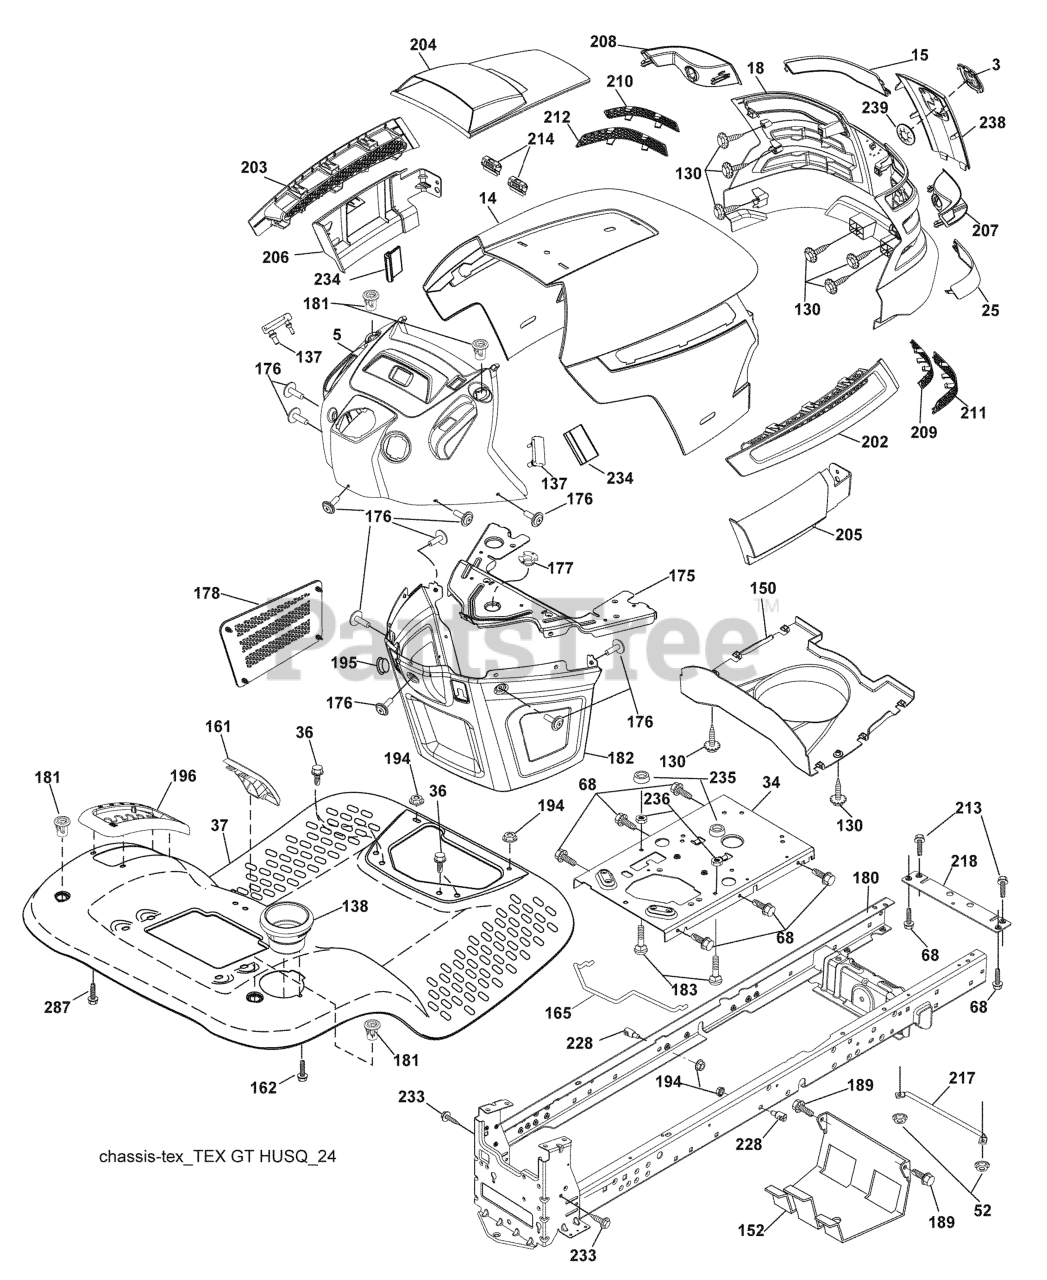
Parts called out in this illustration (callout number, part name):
3	RP LOGO
5	DASH.ASM.HUSQ.GT
14	HOOD
15	LENS.LH.TEX.GT.HUSQ.CL
18	GRILL.ASM.HUSQ.TG/CRD.W/TRIM
25	LENS.RH.TEX.GT.HUSQ.CL
34	PLATE.ENGINE.WELDED.CHASSIS
36	SCREW 5/16"
37	FENDER.TLT.W/CPH.W/FW.ORANGE
52	LOCKNUT
68	Screw 5/16-18 x 1/2
130	SCREW.#10 X 0.750.BOS
137	BUMPER DASH
138	CUPHOLDER.TL.TEX.418
150	AIR.DUCT.HOOD.TEX.GT.HUSQ
152	SHIELD.BROWNING.W/TEX
161	WINDOW FUEL
162	SCREW.HI-LO.CONSOLE
165	SUPPORT.TANK.REAR.W/TEX
175	PLATE.CROSSMEMBER.HUSQ
176	SCREW.#10-24X5/8.RN.QU
177	BUSHING, STEERING
178	CARGO.ASM.NET.TXGT.W/C
180	CHASSIS
181	BUSHING.MNT.FEND.CRGO.
182	DASH.LOWER.COMMON.12V.ADAPTOR
183	BOLT.5/16-18X1-1/4 FULL.THREAD
189	SCREW
194	NUT LOCK HEX FLANGE 5/16-18
195	PLUG.HOLE.DASH.LOWER.12V.BLK
196	RP CONSOLE.ASM.DECKLFT.GR/RBT.
202	VENT.SIDE.HOOD.HUSQ.RH.GREY
203	VENT.SIDE.HOOD.HUSQ.LH.GRAY
204	HOOD VENT
205	SKIRT.HOOD.SIDE.HUSQ.RH.GREY
206	SKIRT.HOOD.SIDE.HUSQ.LH.GREY
207	BEZEL.RH.TEX.GT.HUSQ
208	BEZEL.LH.TEX.GT.HUSQ
209	INSERT.HEX.GRILL.HUSQ.GREY
210	INSERT.HEX.GRILL.HUSQ.
211	INSERT.HEX.GRILL.HUSQ.
212	INSERT.HEX.GRILL.HUSQ.
213	BOLT
214	CLIP.RETAINER.TINNER.
217	ROD.PIVOT.HOOD
218	X-PIECE.HOOD.STOP.NON/
228	STUD.FASTNER.W/ANTI-ROTATE
233	BOLT.SHOULDER
234	BUMPER.HOOD.TEX.HUSQVARNA
235	SPACER FENDER
236	NUT.CENTERLOCK.5/16-
238	TRIM.HUSQ.TG/CRD.SERVICE
287	SCREW 1/4X20
